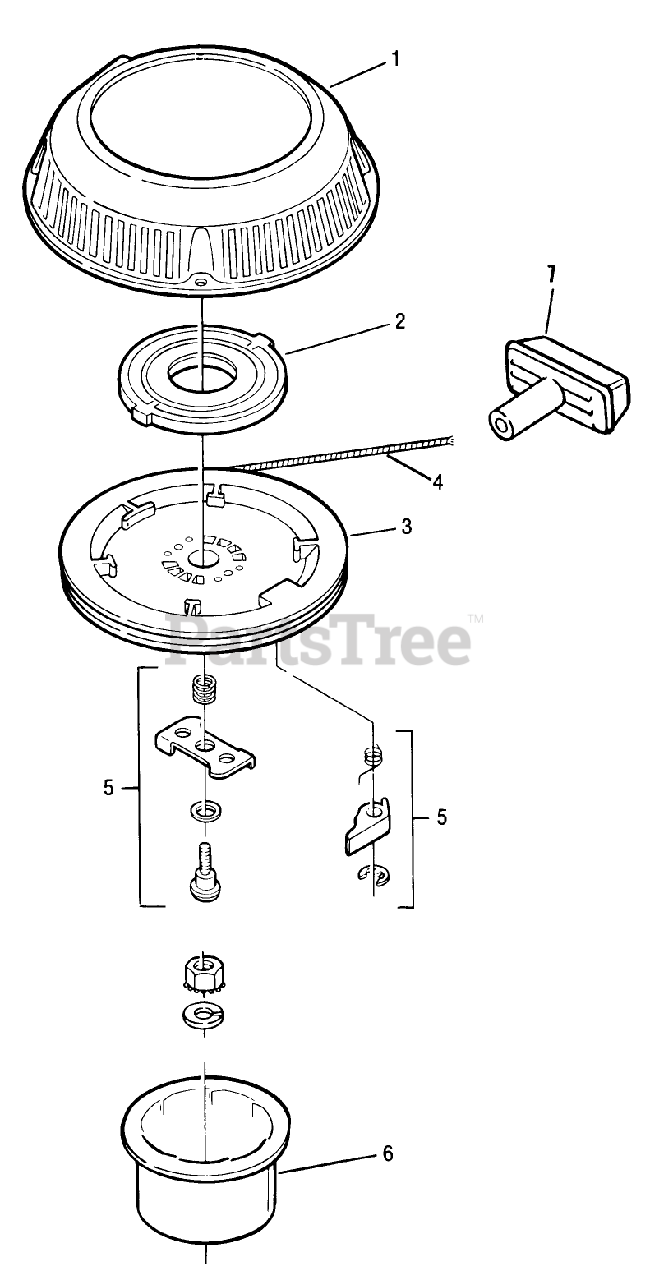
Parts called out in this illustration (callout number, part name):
5	DOG KIT AY.
6	HUB STARTER SM
7	HANDLE START UM&D
